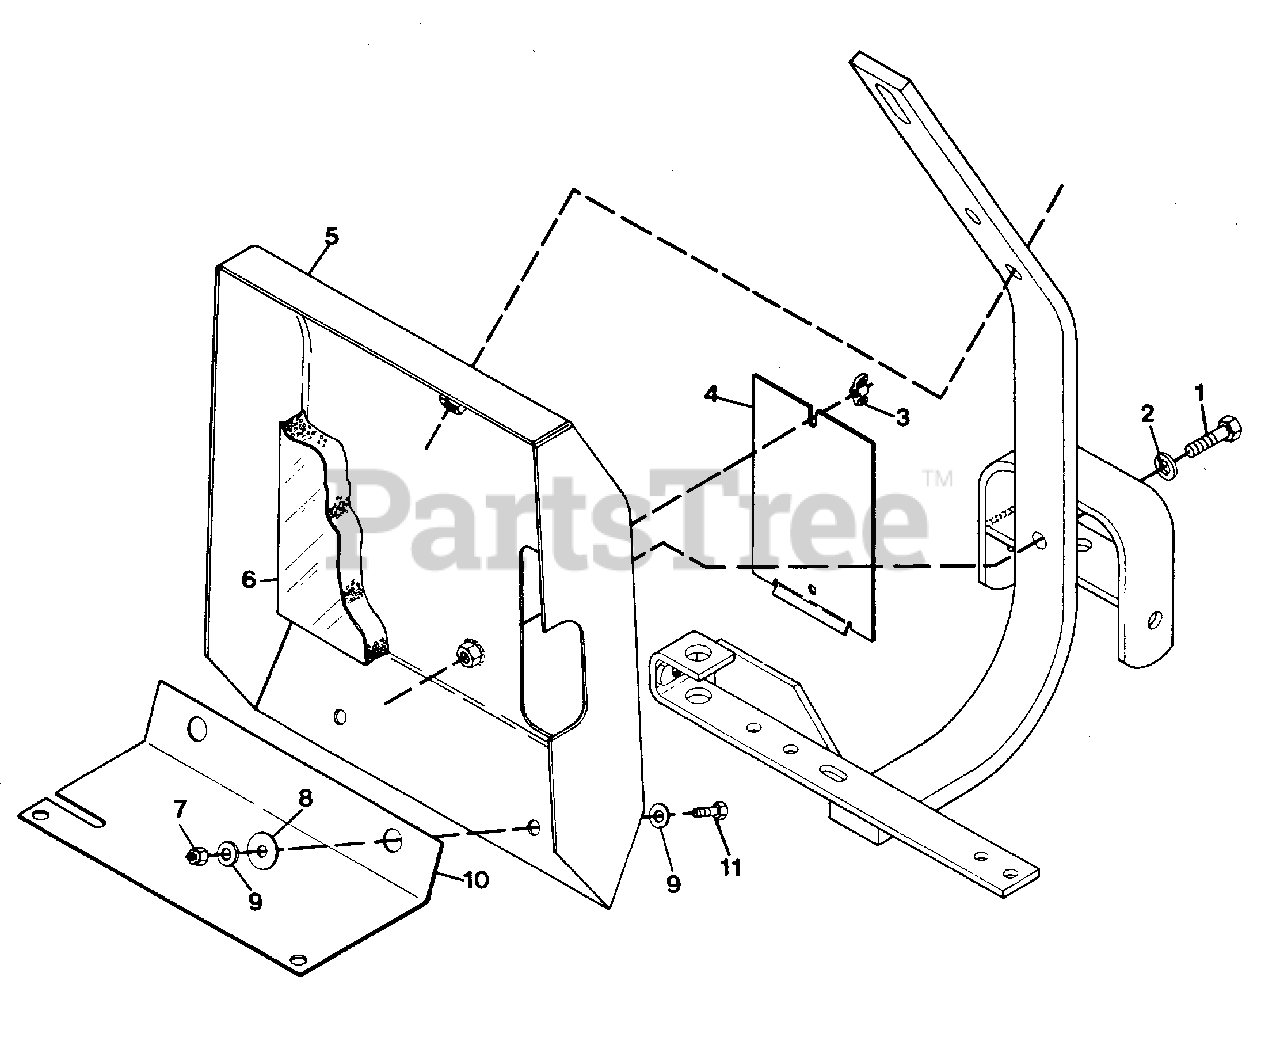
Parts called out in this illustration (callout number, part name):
1	BOLT, HEX 1/2-13X1.25
2	WASHER, LOCK 1/2 REG.
3	NUT, WING 1/4-20
4	PLATE, SILK SCREEN
5	WELDMENT, SOUND SHROUD
6	FOAM, DOOR
6	FOAM, MIDDLE
6	FOAM, R.H.
6	FOAM, L.H.
7	NUT, LOCK 1/4-20
8	WASHER, FLAT .265X1.250X.063
9	WASHER, FLAT .281X.625X.065
10	SCREEN, SOUND
11	BOLT, HEX 1/4-20X.625
